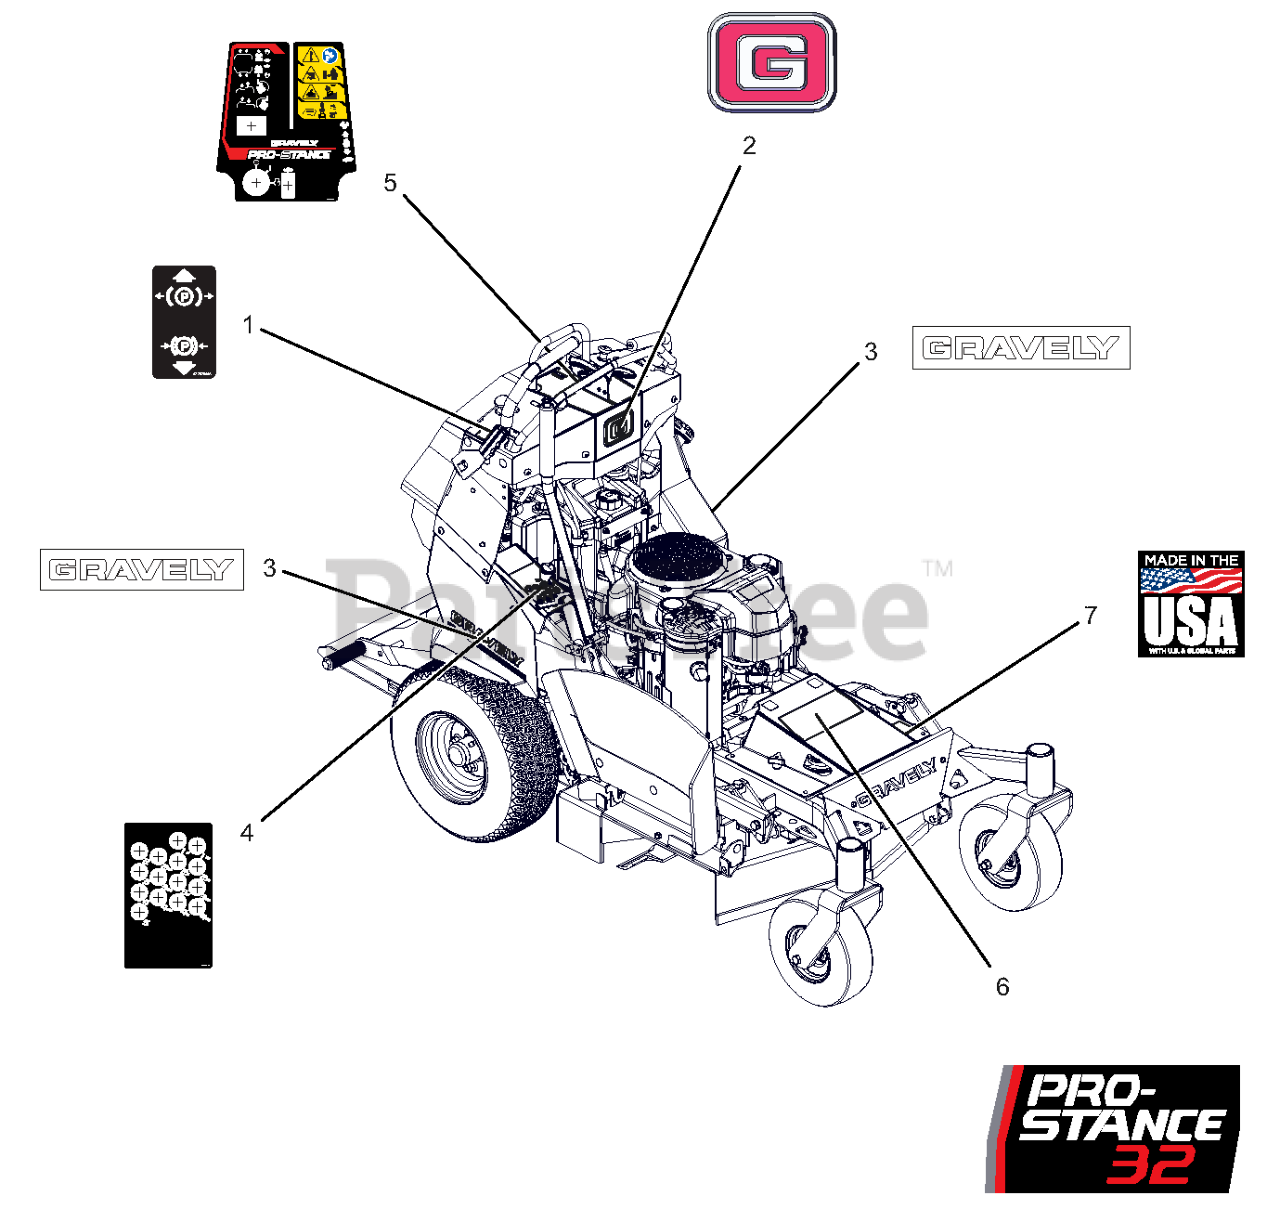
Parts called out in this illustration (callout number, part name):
1	DECAL, PARKING BRAKE LEVER
2	DECAL, GRAVELY BRAND
3	DECAL, 9.5" GRAVELY LOGO
4	DECAL, PRO STANCE - 32-36 HOC
5	DECAL, DASH - PROSTANCE
6	DECAL, PROSTANCE 32
7	DECAL, MADE IN USA
